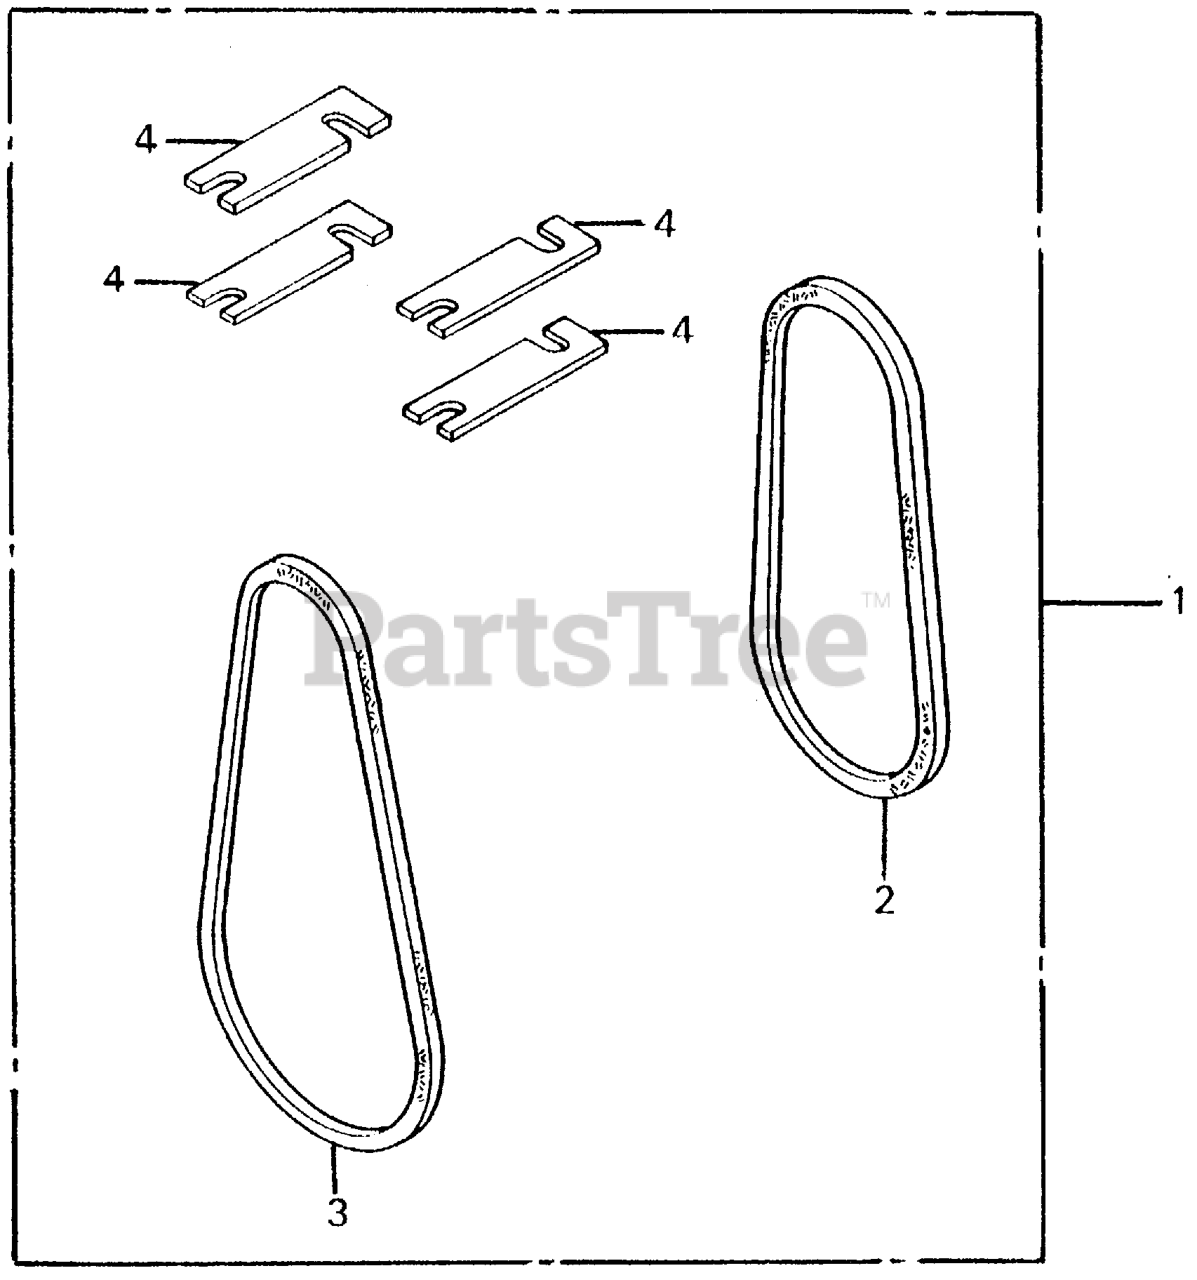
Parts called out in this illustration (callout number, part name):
1	BELT KIT (N/A: SEE COMPONENTS)
2	V-BELT (SA-29)
3	V-BELT (SB-32 R.E.C.)
4	SPACER, MOUNTING
